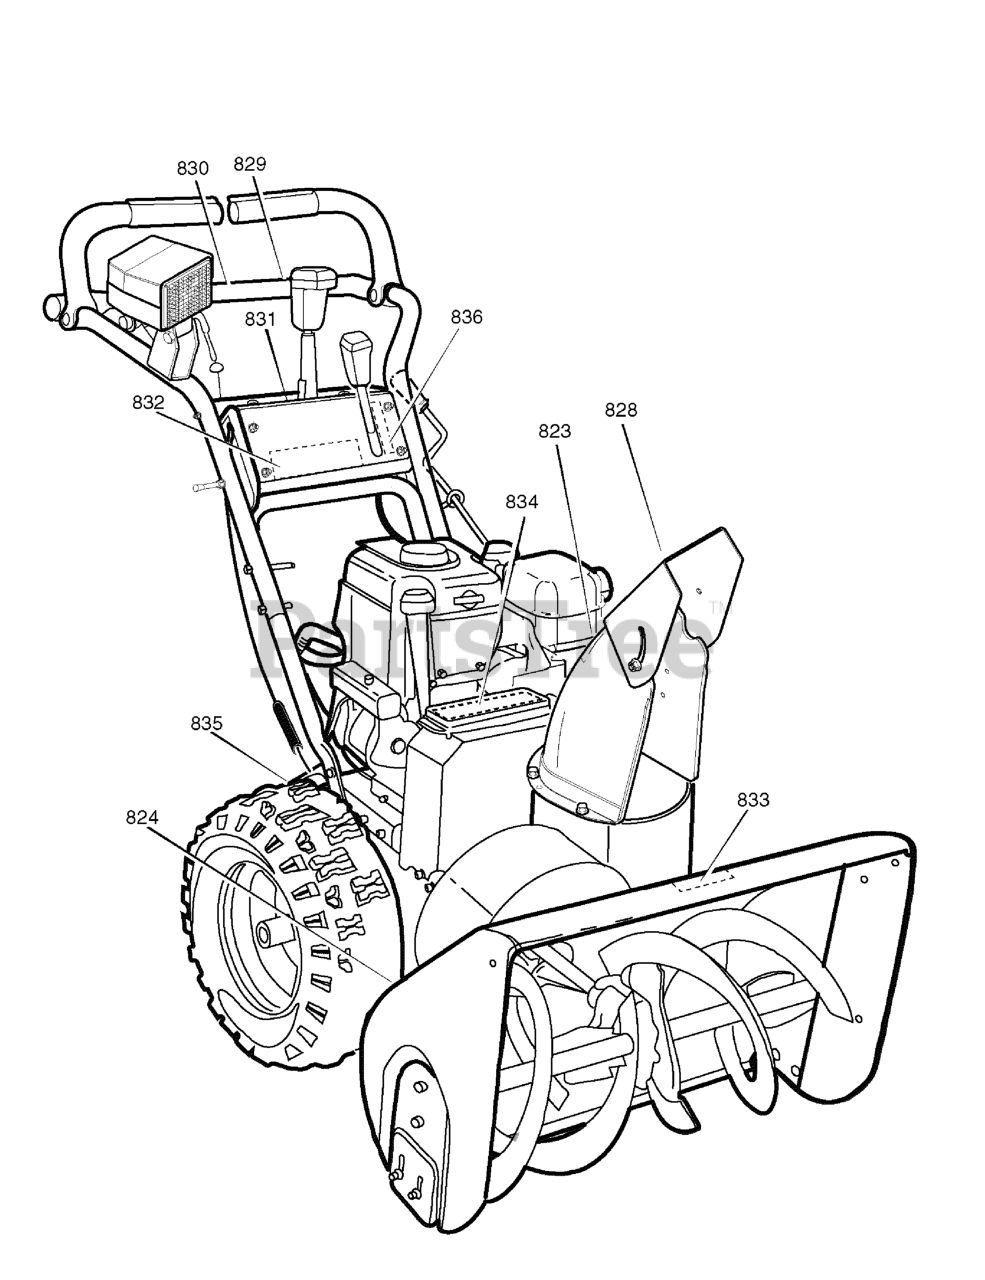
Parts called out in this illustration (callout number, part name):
823	DECAL, Danger Chute, Hand
824	DECAL, Danger, Foot
828	DECAL, Thrown Objects
829	DECAL, Drive Clutch
830	DECAL, Auger Clutch
831	DECAL, Gear Selector
832	DECAL, CRAFTSMAN
833	DECAL, Clean & Clear Brush
834	DECAL, Toolbox Information
835	DECAL, ID Plate
836	DECAL, Remote Chute
